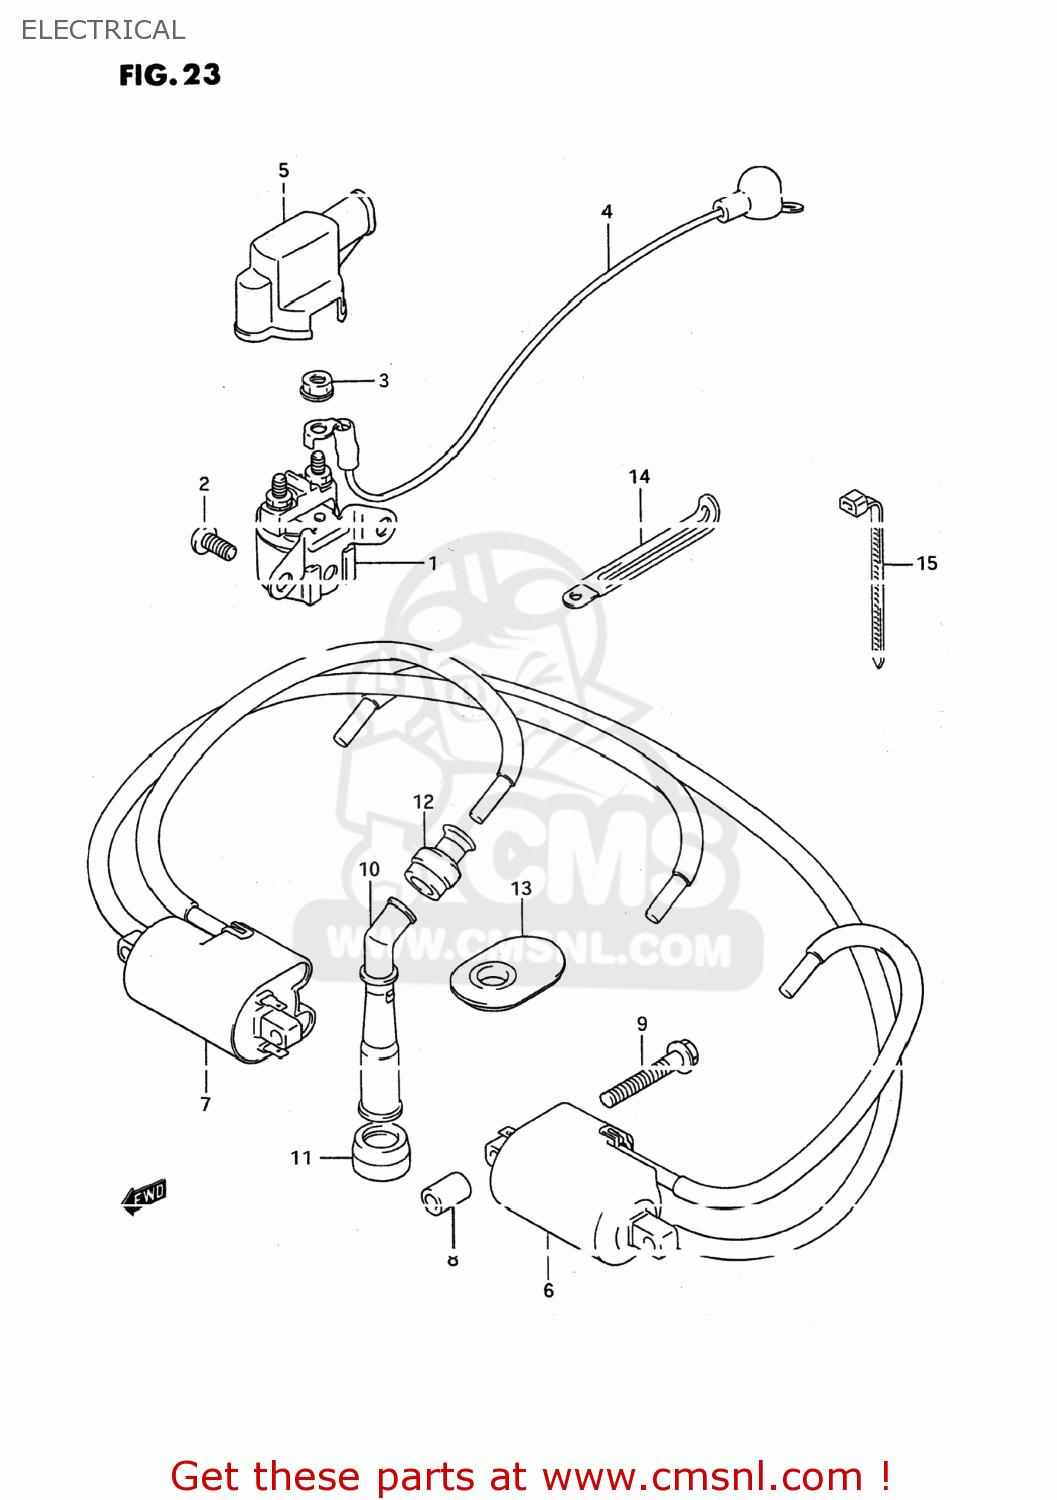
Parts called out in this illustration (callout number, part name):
1	RELAY ASSY,STARTING MOTOR
2	SCREW
3	NUT
4	WIRE,STARTER MOTOR LEAD
5	CAP,STARTER RELAY
6	COIL ASSEMBLY,IGNITION NO
7	COIL ASSEMBLY,IGNITION NO
8	SPACER(6.2X12X16)
9	SCREW
10	CAP,SPARK PLUG
11	SEAL,SPARK PLUG
12	SEAL,HIGH TENSION CORD
13	COVER,SPARK PLUG CAP
14	CLAMP
15	CLAMP(L:165)
